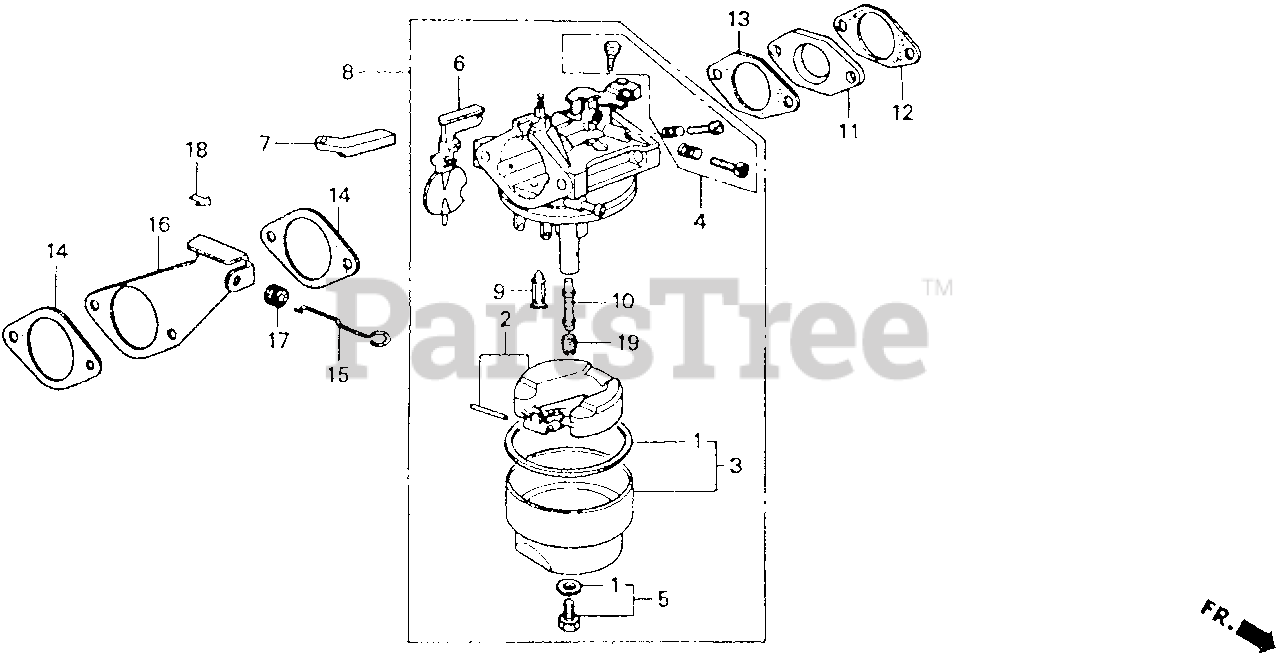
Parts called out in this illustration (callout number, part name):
1	GASKET SET
2	FLOAT SET
3	CHAMBER SET, FLOAT
4	SCREW SET A
5	SCREW SET B
6	CHOKE SET
7	ARM, CHOKE LEVER
8	CARBURETOR ASSY.
9	VALVE, FLOAT
10	NOZZLE, MAIN
11	INSULATOR, CARBURETOR
12	GASKET, INSULATOR
13	GASKET, CARBURETOR
14	GASKET, AIR CLEANER
15	ROD, CHOKE CONTROL
16	STAY, CHOKE CONTROL
17	GROMMET, CHOKE ROD
18	MARK, CHOKE
19	JET, MAIN (#55)
19	JET, MAIN (#58)
19	JET, MAIN (#60)
19	JET, MAIN (#62)
19	JET, MAIN (#65)
